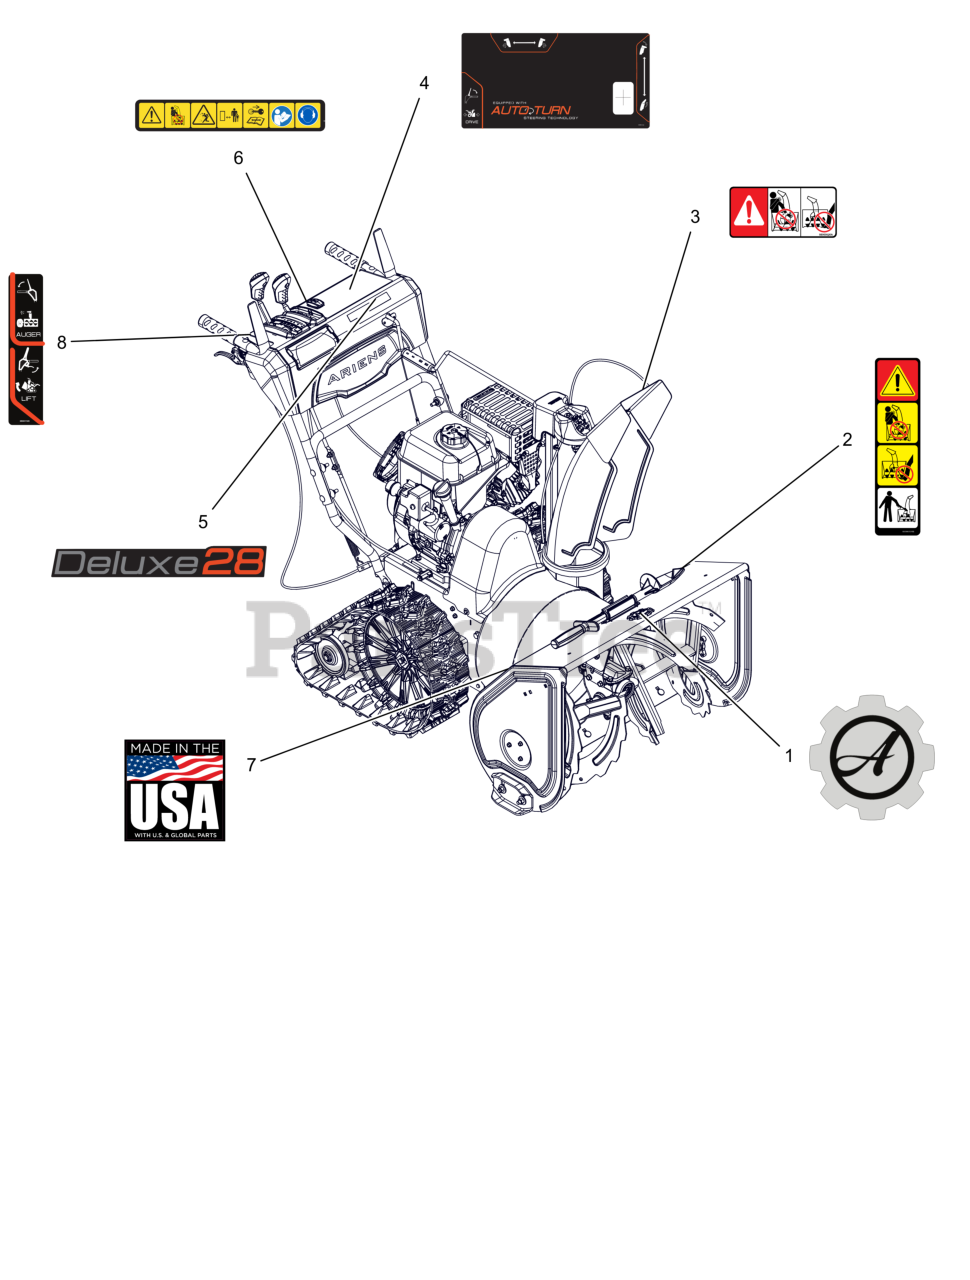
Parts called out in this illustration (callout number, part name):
1	DECAL, ARIENS - GEAR BADGE
2	DECAL, DANGER - ROTATING PARTS
3	DECAL, DANGER
4	DECAL,CONTROL-LG ID
5	DECAL, DASH - DELUXE 28
6	DECAL,DASH - SAFETY
7	DECAL, MADE IN USA
8	DECAL,CONTROL-RH TRACK
